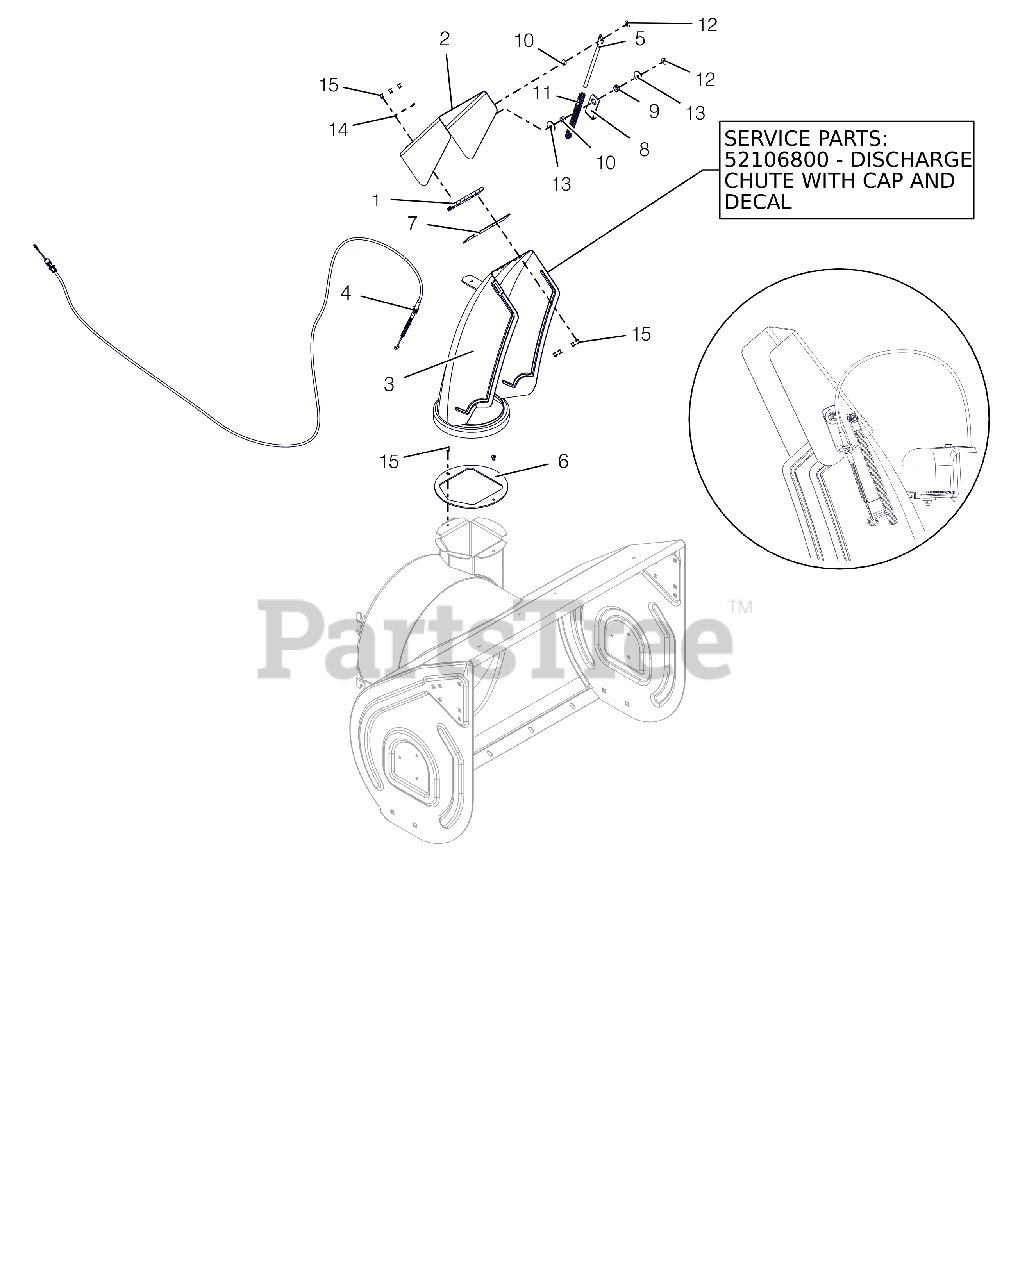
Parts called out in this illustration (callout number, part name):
2	CAP, LARGE REMOTE (W/DECAL)
3	CHUTE,DISCHARGE,NOTCHED,QT
3	KIT, DISCHARGE CHUTE W/DEF QT2
4	CABLE, DEFLECTOR - DELUXE
5	ROD, DEFLECTOR CAP
6	BAFFLE, DISCHARGE NECK
7	CAP SEAL 5.50
8	BRACKET, CABLE ANCHOR
9	BUSHING, POLYLINER-.50 SNAPIN
10	BSHG-SLV .265X.500X.219
11	SG-COMP .08X.40X6.50 14#/IN
12	@NUT-LK-CTR-FLG .25-20 YWZC
13	WSHR-FL-STL .281X1.000X.063
14	WSHR-FL-STL .196X.500X.06 YZ
15	RVT-POP .187 YZ
